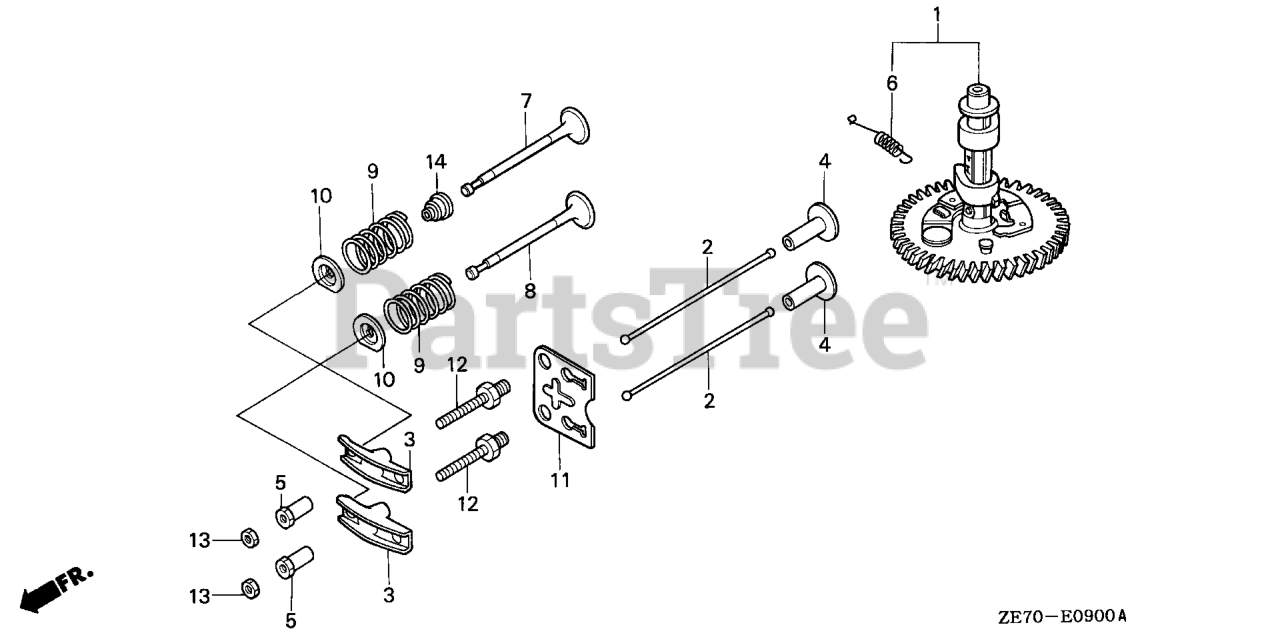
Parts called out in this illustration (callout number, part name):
1	CAMSHAFT ASSY.
2	ROD, PUSH
3	ARM, VALVE ROCKER
4	LIFTER, VALVE
5	PIVOT, ROCKER ARM
6	SPRING, WEIGHT RETURN
7	VALVE, IN.
8	VALVE, EX.
9	SPRING, VALVE
10	RETAINER, VALVE SPRING (EXHAUST SIDE)
11	PLATE, PUSH ROD GUIDE
12	BOLT, PIVOT (8MM)
13	NUT, PIVOT ADJ.
14	SEAL, VALVE STEM
